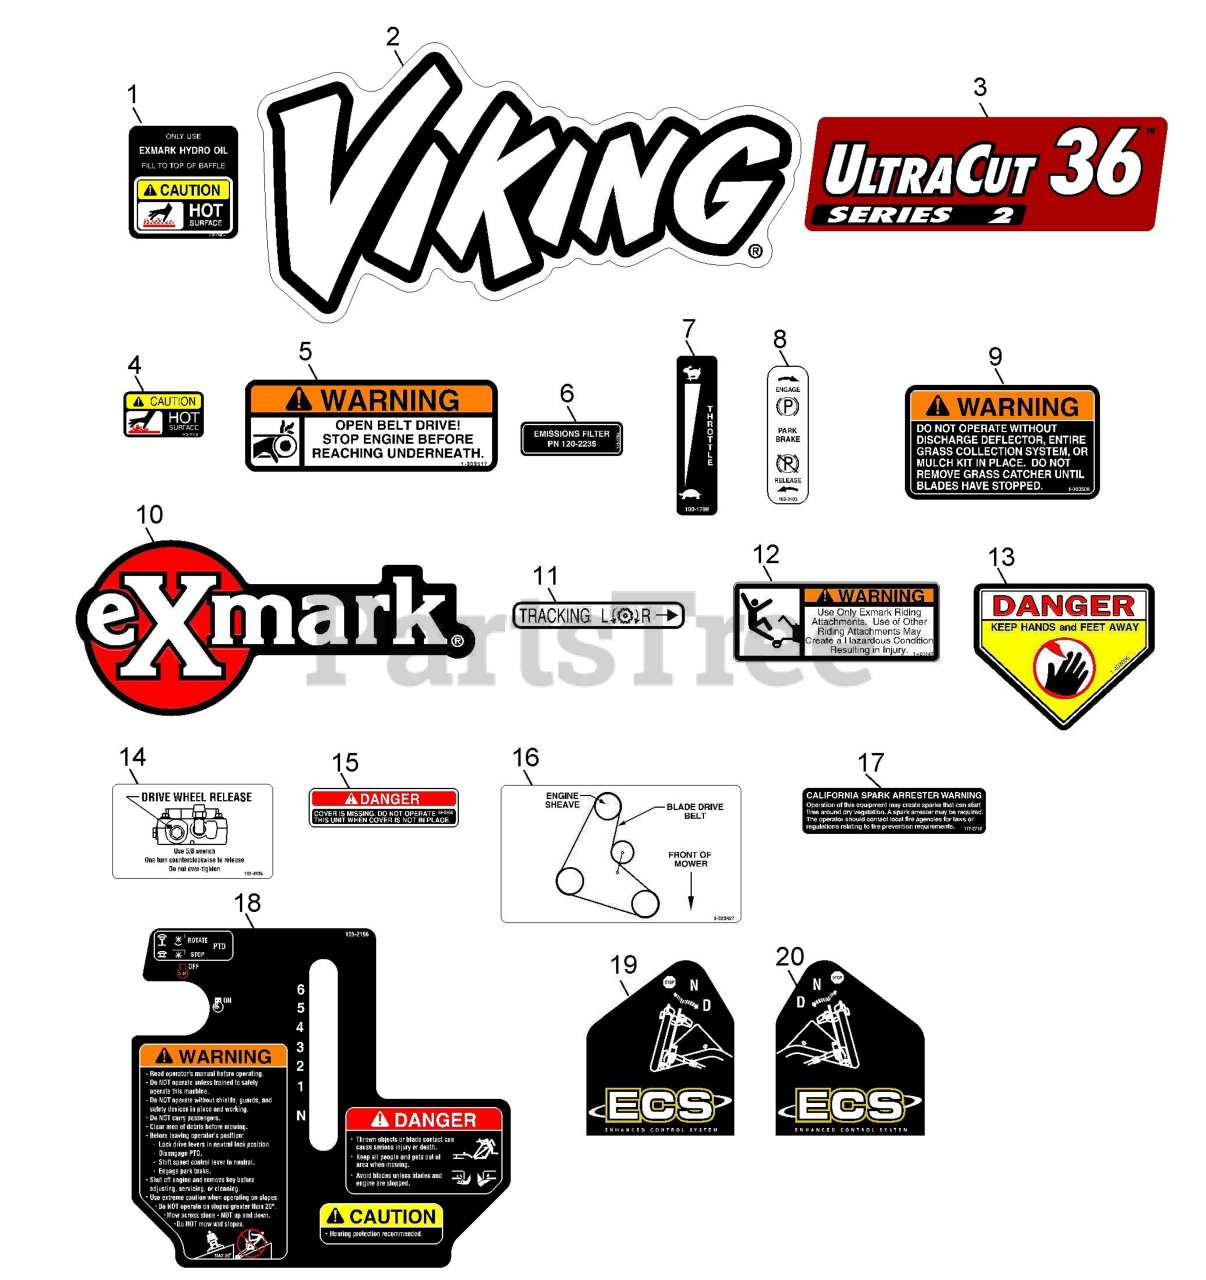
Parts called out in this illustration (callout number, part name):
1	DECAL-HYDRAULIC TANK
2	DECAL,VH MODEL
3	DECAL-ULTRACUT 36 SERIES
4	DECAL-CAUTION
5	DECAL,BELT DRIVE
6	DECAL-FILTER, EMISSIONS
7	DECAL,THROTTLE ONLY
8	DECAL-BRAKE, PARK
9	DECAL-WARNING, DISCHARGE
10	DECAL,EXMARK LOGO
11	DECAL,TRACKING ADJUST
12	DECAL,SULKY WARNING
13	DECAL-DANGER
14	DECAL,DRIVE RELEASE
15	DECAL-COVER, MISSING
16	DECAL,BELT ROUTING 32/36
17	DECAL-ARRESTER, SPARK
18	DECAL,CONSOLE VH ECS
19	DECAL,LH ECS INSTRUCTION
20	DECAL,RH ECS INSTRUCTION
